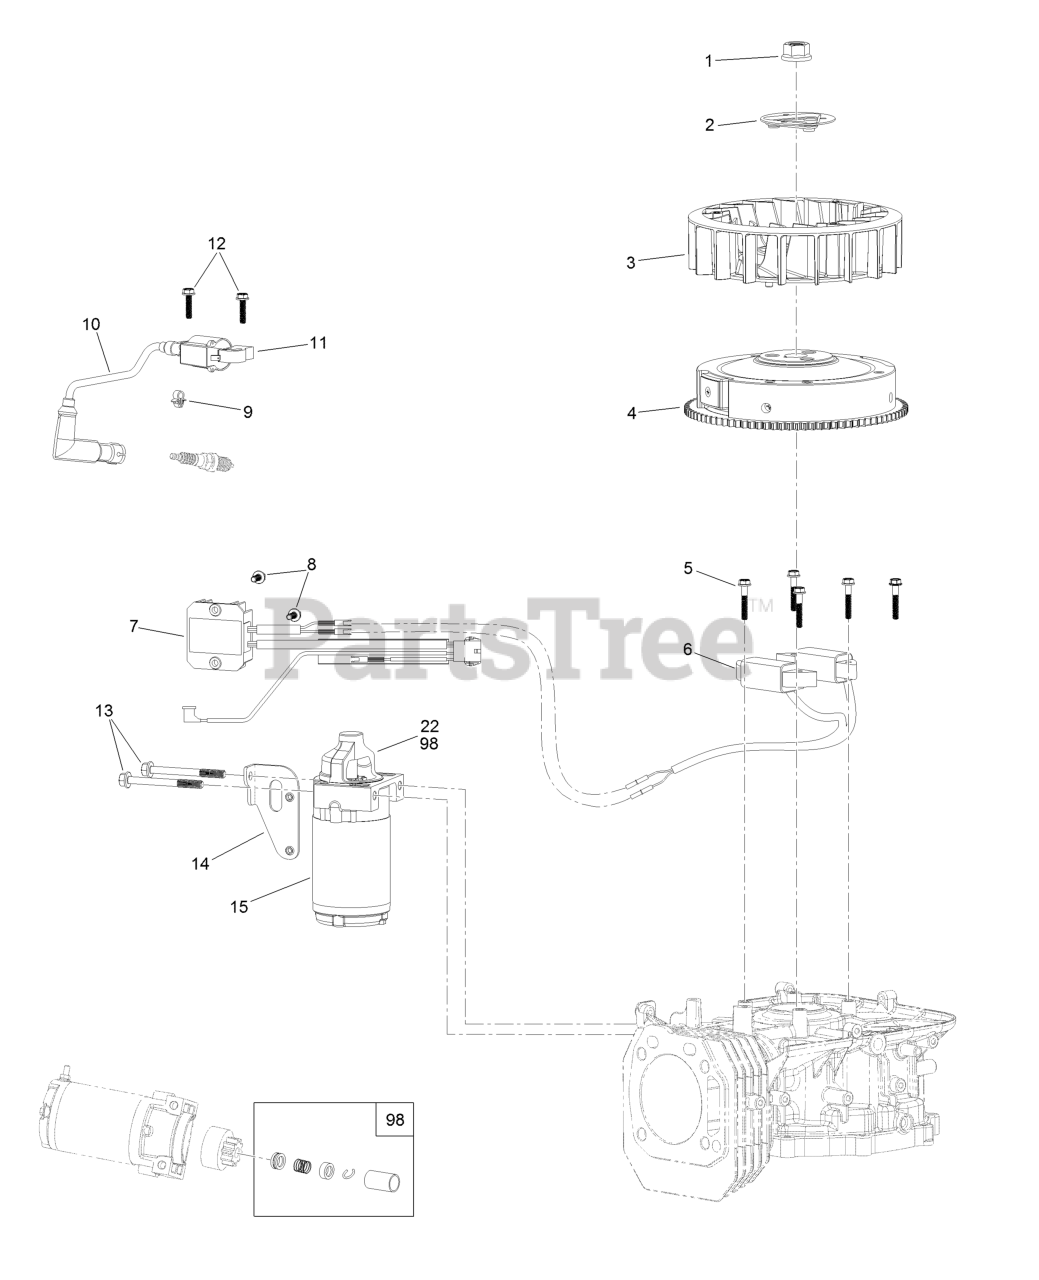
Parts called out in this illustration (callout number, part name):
1	NUT-FLANGE
2	PULLEY-STARTER
3	FAN-COOLING
4	FLYWHEEL
5	SCREW-HHF
8	SCREW-HHF
9	CLAMP-WIRE
10	BOOT-PLUG, SPARK
12	SCREW-HHF
13	SCREW-HHF
14	BRACKET-STARTER
15	MOTOR-STARTER
22	PINION-STARTER
98	STARTER REPAIR KIT
